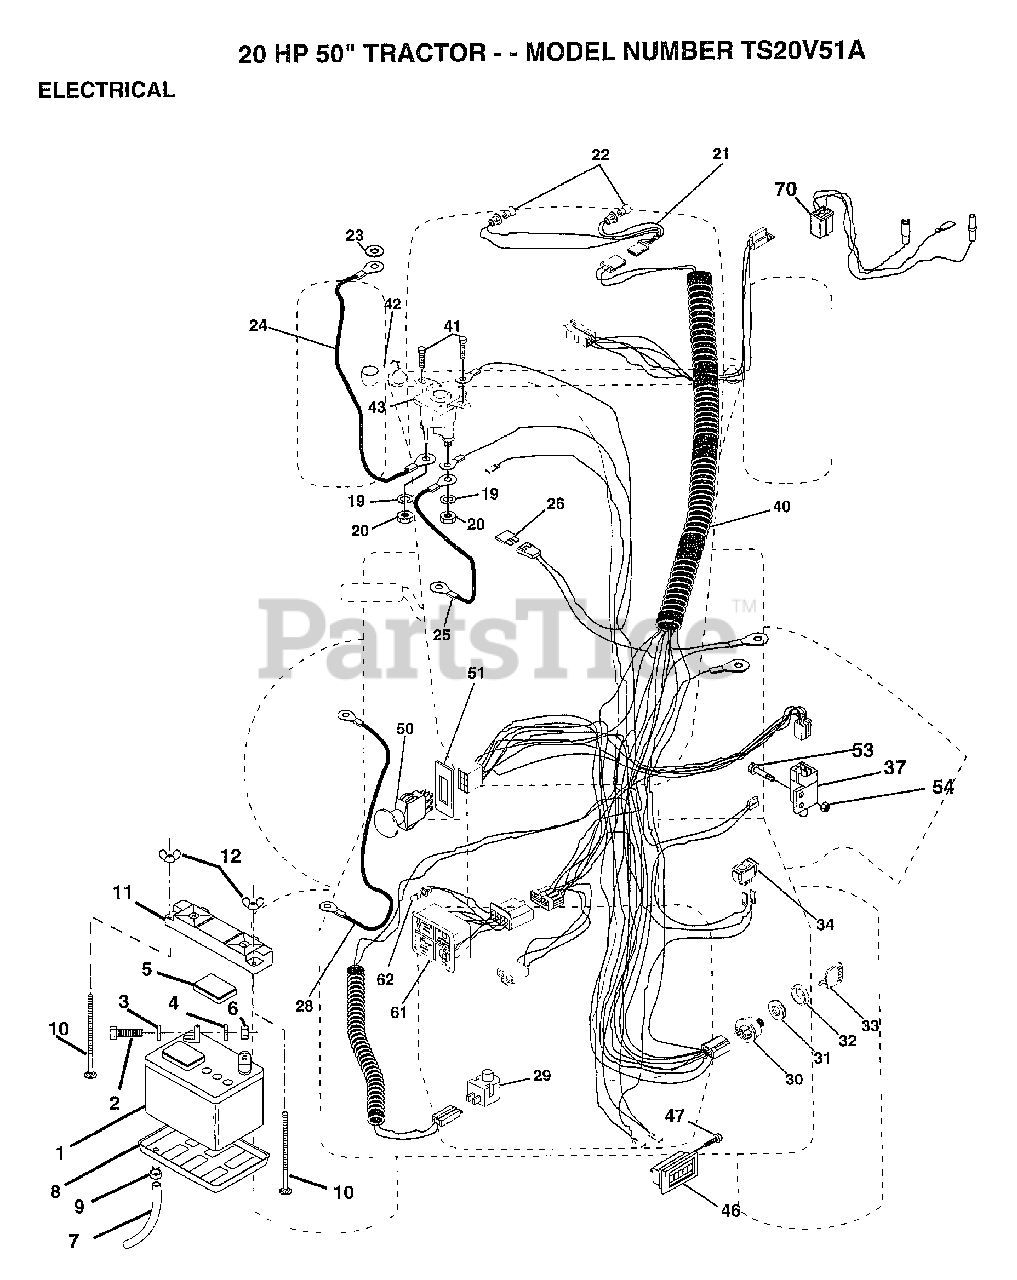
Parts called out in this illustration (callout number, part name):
2	BOLT LT
3	LOCKWASHER
4	WASHER
5	"CAP,BATTERY "
7	"DRAIN TU T, BATT"
8	"TRAY T, BATTERY"
9	HOSE CLAMP T
10	BOLT
20	NUT
22	HEADLAMP BULB
23	LOCKWASHER
24	CABLE-BATTERY T
25	CABLE-BATTERY T
26	FUSE HYT
28	CABLE T
29	SWITCH SEAT
32	COVER KEY SWITCH
33	KEY MLD GEN DELTA
34	SWITCH LT
37	SWITCH INTERLOCKT
40	HARNESS IGNITION
41	SCREW
46	HOUR METER T
47	SCREW
51	RING RETAIN PTO
53	SCREW
54	"NUT,KEPS"
61	LIGHT.PKG.ASM.
62	BULB LIGHT T
70	HARNESS.ENG.VANII
